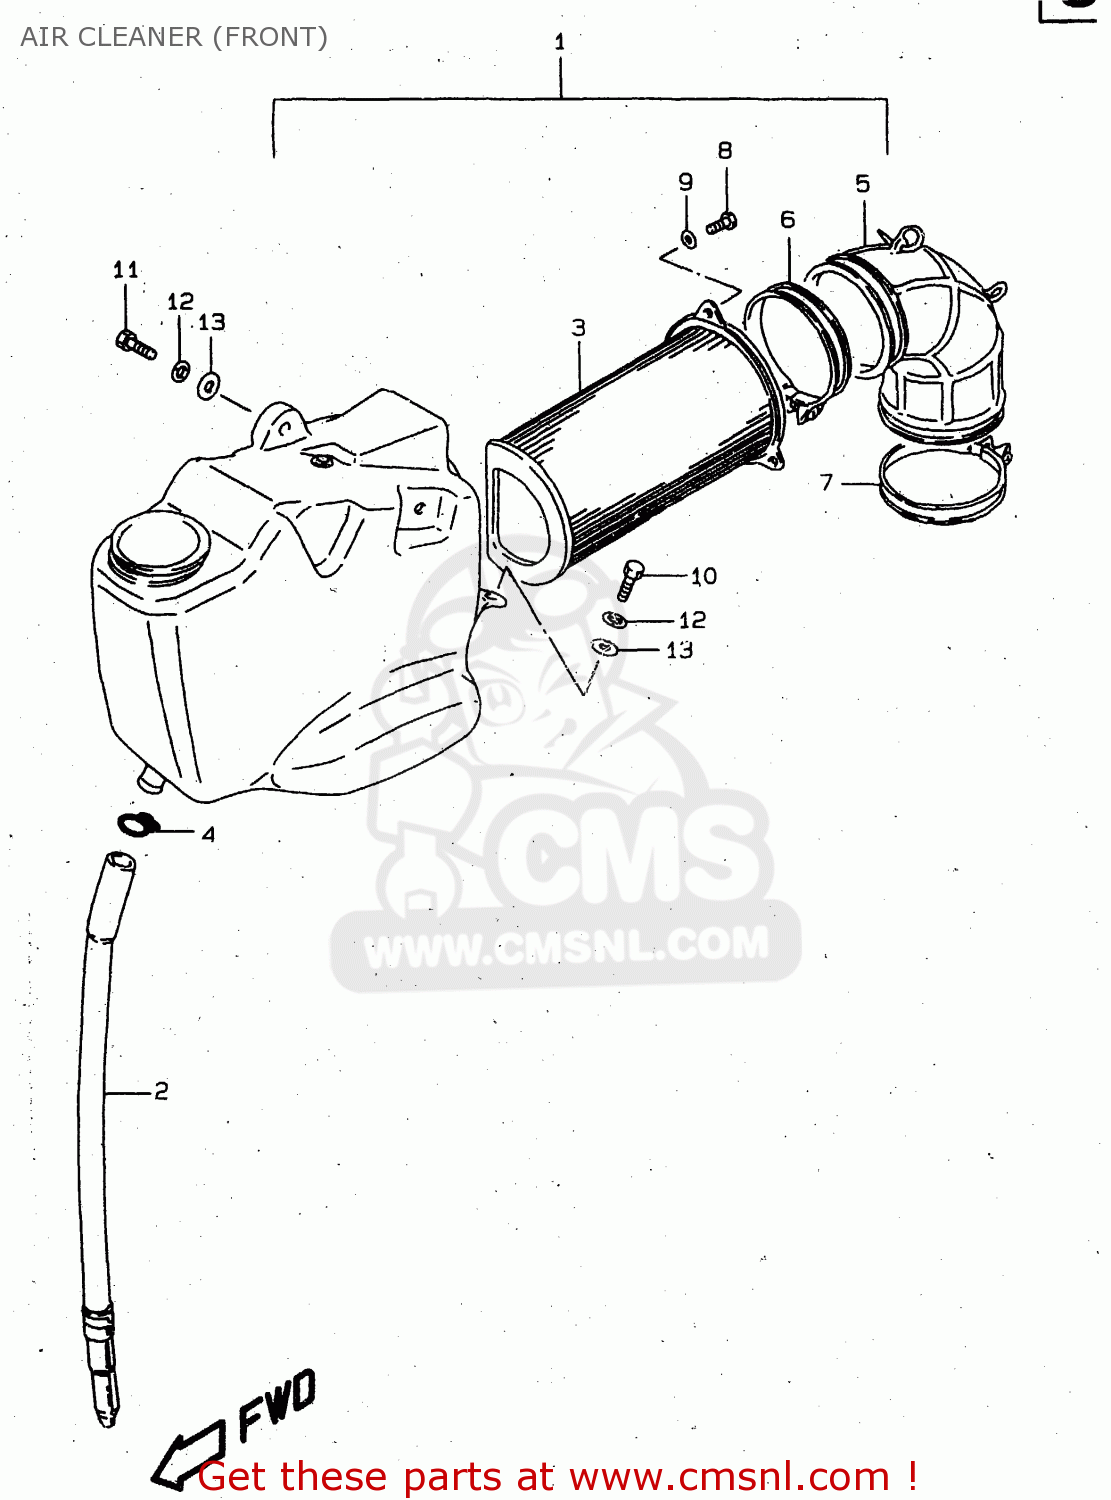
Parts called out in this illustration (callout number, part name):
1	CLEANER ASSY,AIR FR
2	TUBE,DRAIN
3	FILTER ASSY
4	CLIP
5	TUBE,AIR CLEANER OUTLET
6	CLAMP
7	CLAMP
8	SCREW
9	WASHER,LOCK
10	BOLT
11	BOLT, REAR
